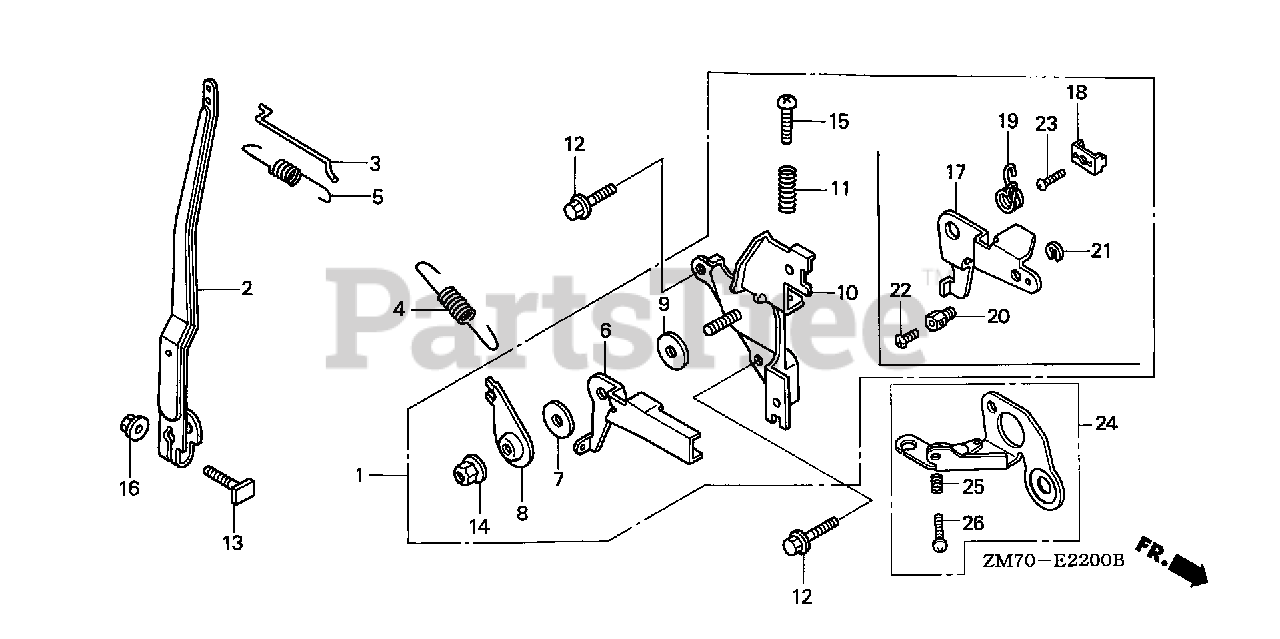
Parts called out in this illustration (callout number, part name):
1	CONTROL ASSY.
2	ARM, GOVERNOR
3	ROD, GOVERNOR
4	SPRING, GOVERNOR
5	SPRING, THROTTLE RETURN
6	LEVER, CONTROL
7	SPRING, LEVER
8	WASHER, CONTROL LEVER
9	SPACER, CONTROL LEVER
10	BASE, CONTROL
11	SPRING, CONTROL ADJUSTING
12	BOLT, FLANGE (5X12)
13	BOLT, GOVERNOR ARM
14	NUT, SELF-LOCK (6MM)
15	SCREW, PAN (5X20)
16	NUT, FLANGE (6MM)
